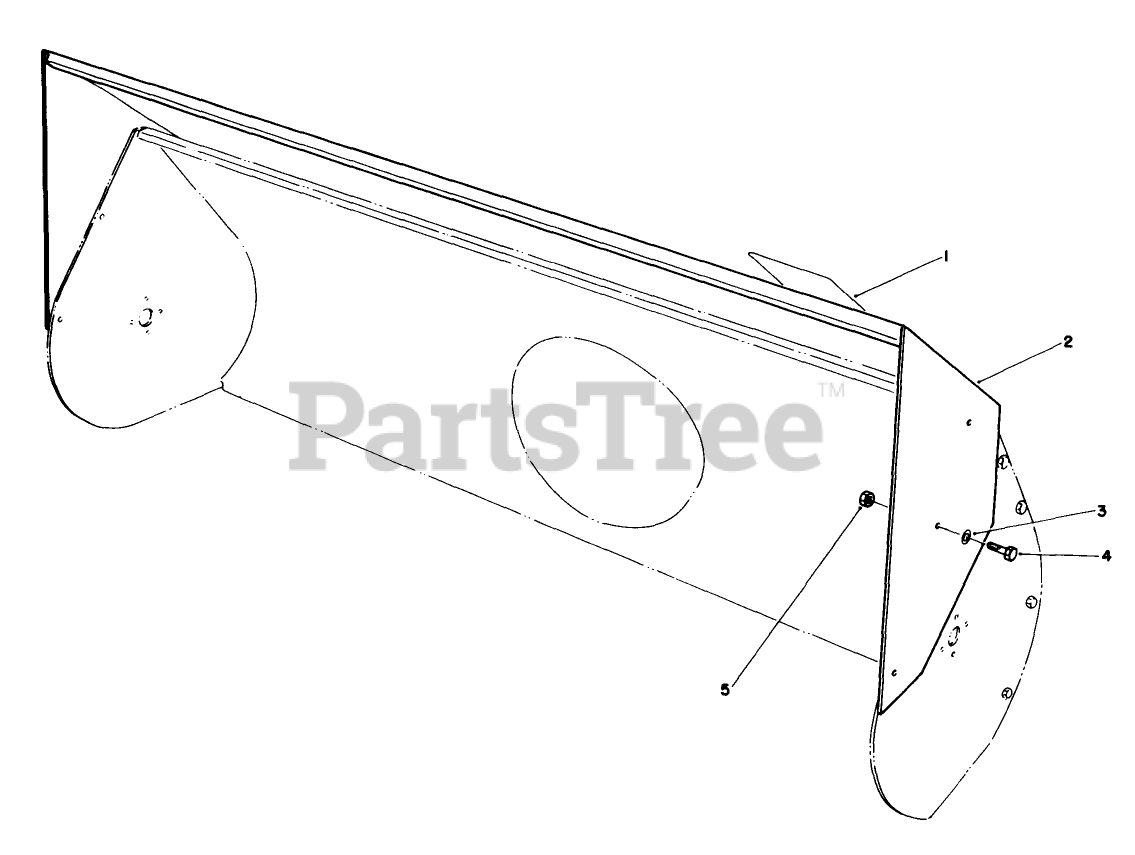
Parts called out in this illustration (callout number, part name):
1	Decal
3	WASHER-FLAT
4	SCREW-HH
5	NUT-LOCK, NI
